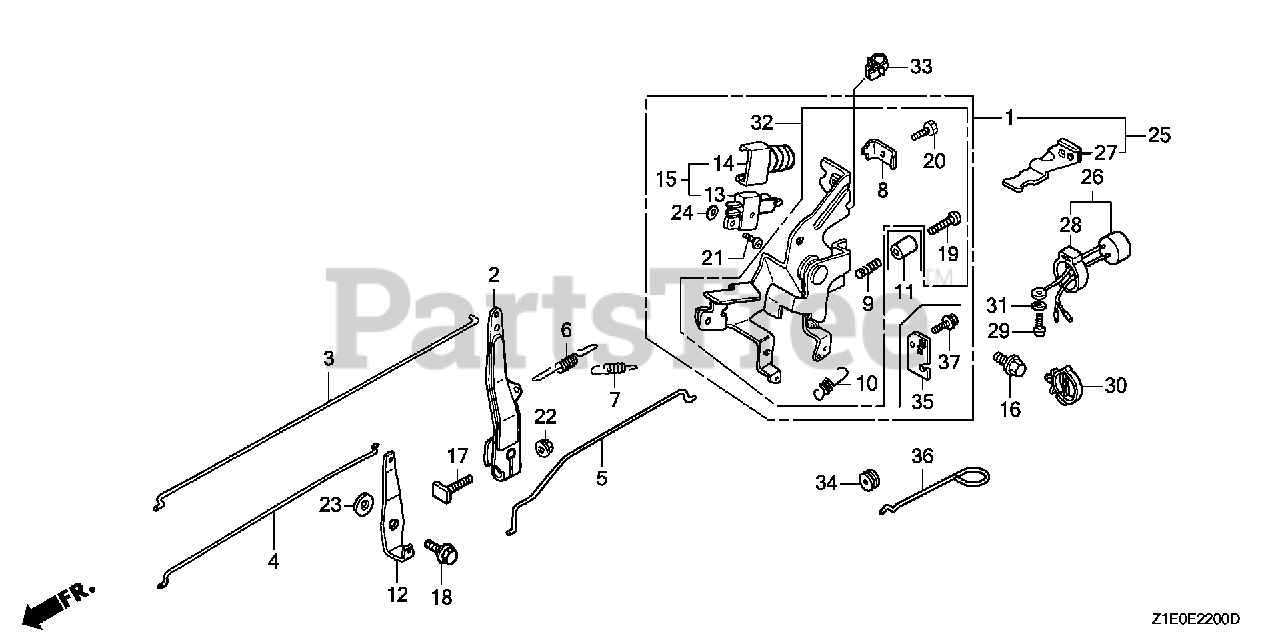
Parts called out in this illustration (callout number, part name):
2	ARM, GOVERNOR
3	ROD, GOVERNOR
4	ROD, CHOKE
5	ROD, JOINT
6	SPRING, GOVERNOR
7	SPRING, GOVERNOR PRIMARY
8	HOLDER, CABLE
9	SPRING, CONTROL ADJUSTING Use from Engine SN 2327377.
10	SPRING, CABLE RETURN
12	LEVER, CHOKE JOINT
13	SWITCH ASSY., ENGINE
14	COVER, SWITCH
15	SWITCH ASSY., ENGINE STOP
16	BOLT, FLANGE (6X12) (CT200)
17	BOLT, GOVERNOR ARM
18	BOLT, FLANGE (6MM)
19	SCREW, PAN (5X20)
20	BOLT, RECESSED (5X16)
21	SCREW, PAN (4X14)
22	NUT, FLANGE (6MM)
23	WASHER, PLAIN (6MM)
24	WASHER, SPRING (4MM)
25	CONTROL ASSY. (ALT)
26	BUZZER ASSY.
27	STAY, BUZZER
28	SUSPENSION, AUDIBLE PILOT
29	SCREW, TAPPING (5X8)
30	CLIP, WIRE HARNESS
31	WASHER, SPRING (5MM)
